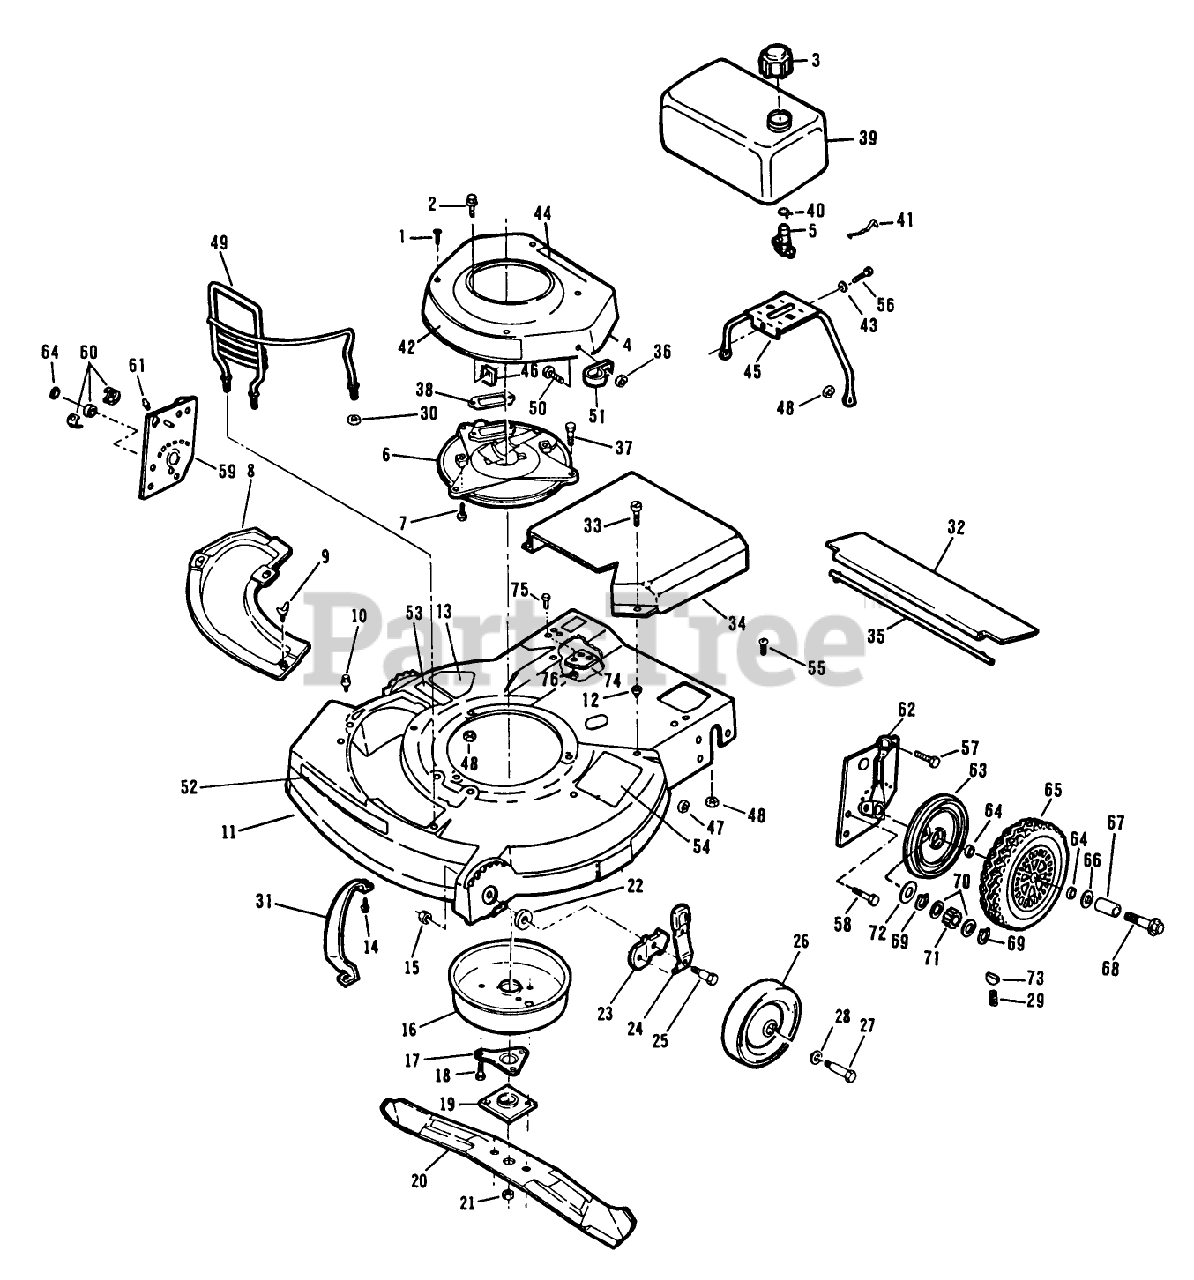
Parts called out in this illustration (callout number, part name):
1	SCREW - SELF TAPPING
2	SCREW SEMS SM
3	FUEL CAP & INSERT
5	VALVE&SCREEN SM
6	PLATE F
7	SCREW V
9	WING SCREW LAWRE
15	LOCKNUT
16	MUFFLER COVER F
17	SUPPORT F
18	SCREW
19	PLATE AND COLLAR ASM
21	NUT-BLADE
22	WASHER
24	SPRING ARM ASM
25	BOLT
26	WHEEL AND TIRE ASM
27	BOLT WHEEL
28	SPACER
29	SPRING
30	NUT-LOCK F
31	BAR-TOE
33	SCREW SEMS TRM HEX HD
34	Cover-Drive
36	LOCKNUT E
37	SCREW-HH
40	CLAMP - HOSE S
41	SPRING
43	WASHER S
46	PUSHNUT F
47	NUT-LOCK F
48	LOCKNUT E
56	BOLT F
57	SCREW
60	REAR AXLE BEARING
61	**FITTING LINCOLN
64	WASHER
65	WHEEL AND TIRE ASM
69	RET RING
70	SPACER/GR ALGHNY
71	PINION BROCKWAY
72	THRUST WASHER
73	KEY
74	BOLSTER
76	NUT-LOCK F
